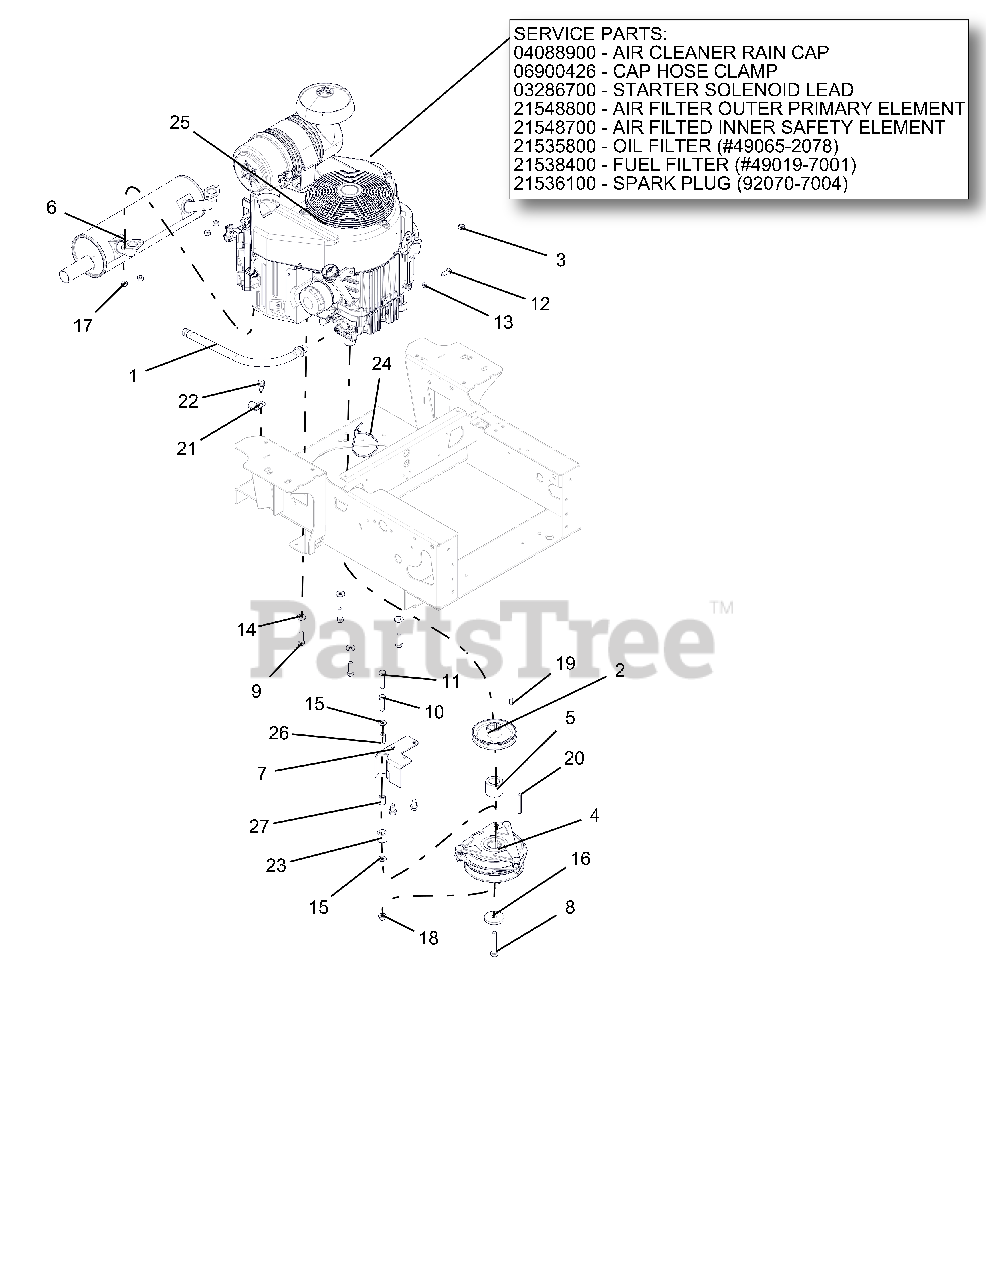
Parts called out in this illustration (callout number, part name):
1	HOSE, OIL DRAIN
2	PULLEY, 4.50 OD X 1.127 ENGINE-BLACK
3	CLAMP, FUEL LINE
4	CLUTCH, OGURA GT2.5-FE02
5	SPCR, 1.125 X 1.75 X 1.400
6	MUFFLER, KAWASAKI FX24/26 HP
7	BRKT, CLUTCH STOP
8	BLT-HEX .44-20X2.50 GR5 EP80 YWZC
9	BLT-HEX .38-16X1.25 GR5 YWZC NYTORQ
10	BLT-HEX .38-16X1.50 GR5 YWZC
11	BLT-HEX .38-16X1.75 GR5 YWZC
12	@BLT-HEX M8-1.25X20 YWZC
13	WSHR-LK .31X.078 REG YWZC
14	WSHR, 3/8" SPRING DISC
15	WSHR-FL-STL.406X.812X.065 YWZ
16	WSHR-FL-STL .469X2.00X.25 YWZC
17	NUT-LK-TOP M8-1.25 YWZC
18	NUT, LK-TOP-FLG .38-16 YWZC
19	KEY-SQ .250X.250X.625
20	KEY, .25X.25X2.25
22	SCR-TAP .38-16X.75 HWH TR YWZ
23	BUMPER, RUBBER .62 X 1.0 X .88 LG
24	CABLE, TIE 5.50 LG
25	ENGINE, KAWASAKI FX730
25	AIR CLEANER RAIN CAP
25	CAP HOSE CLAMP
25	STARTER SOLENOID LEAD
25	AIR FILTER OUTER PRIMARY ELEMENT
25	AIR FILTER INNER SAFETY ELEMENT
25	OIL FILTER (#49065-2078)
25	FUEL FILTER (#49019-7001)
25	SPARK PLUG (#92070-7004)
26	BUSH.,S.391X.622X.95 ST REV A
27	BUSHING, SLV .407X.625X.813
